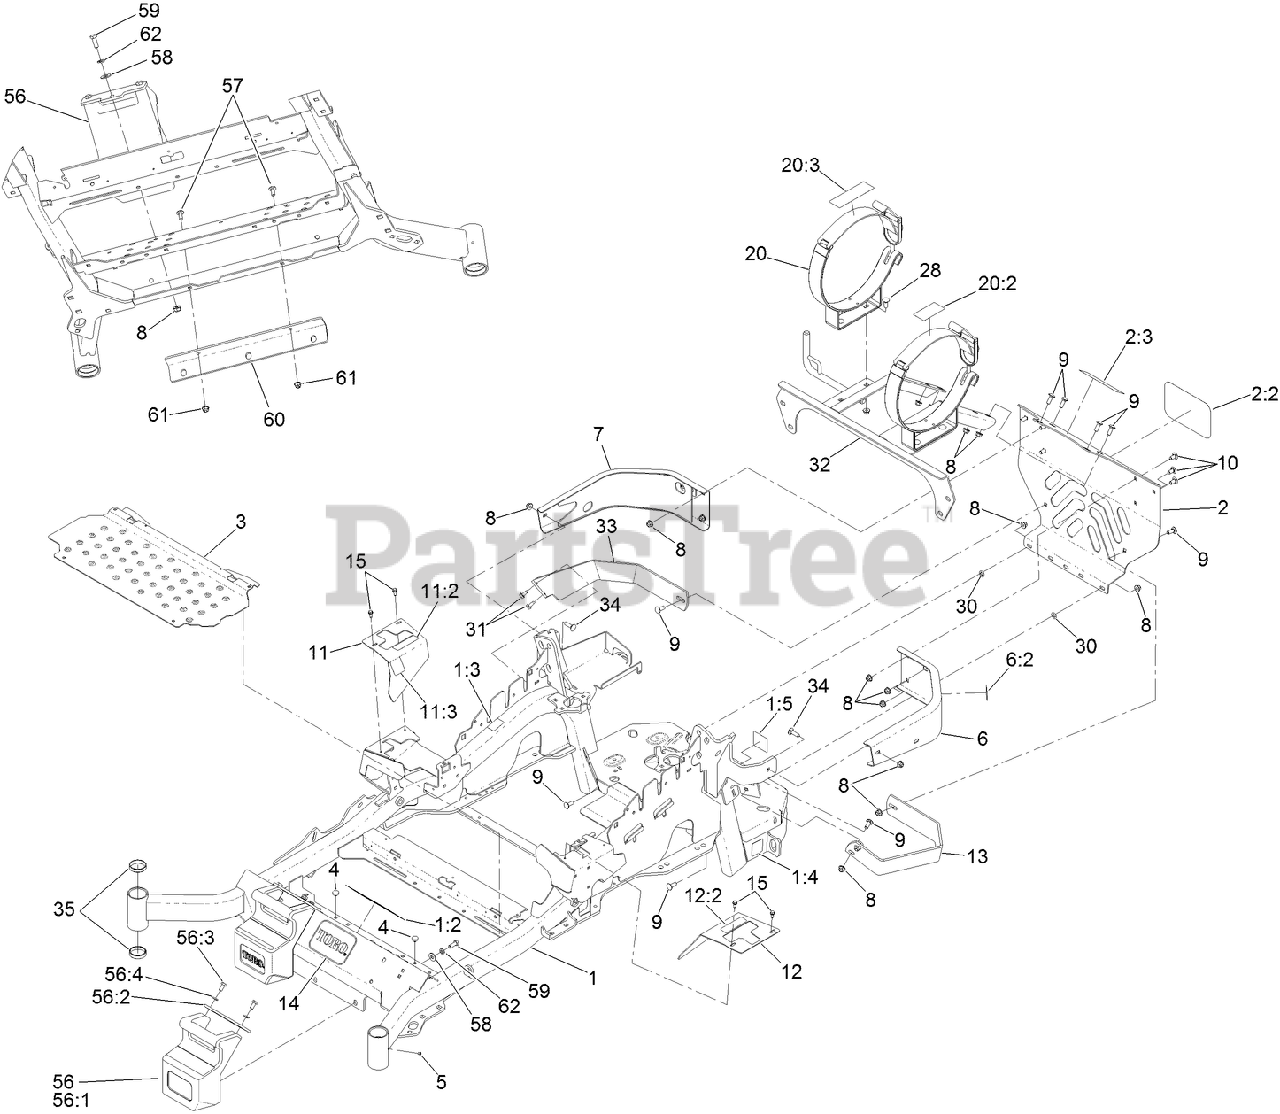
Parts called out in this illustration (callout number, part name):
1	MAINFRAME ASM
1:2	DECAL-DANGER
1:3	DECAL-WARNING
1:4	DECAL-HAZARD, PINCHED FINGER
1:5	DECAL-SPARK ARRESTER
2	LPG REAR GUARD ASM
2:2	DECAL
2:3	DECAL-LPG FUEL TANK REPLACEMENT
3	FLOORPAN
4	BUMPER
6	LH BUMPER ASM
6:2	DECAL-WARNING
7	BUMPER-RH
8	NUT-HF, NI
9	SCREW-CARR
10	SCREW-CARR
11	RH MOTION CONTROL COVER ASM
11:2	DECAL-CONTROL, MOTION
11:3	DECAL-PARK BRAKE, CE
12	LH MOTION CONTROL COVER ASM
12:2	DECAL-CONTROL, MOTION
13	GUARD-MUFFLER
14	DECAL
15	SCREW-HWH
20	TANK BRACKET ASM (SET)
20:2	DECAL-LPG WARNING
20:3	DECAL-LPG TANK SPEC
28	BOLT-CARR
30	NUT-PUSH
31	SCREW-HWHTF
32	SUPPORT-LPG TANK
33	STRAP-GUARD
34	BOLT-CARR
35	CUP-BEARING
56	WEIGHT ASM
56:1	WEIGHT-43 LB
56:2	TAB-SUPPORT, WEIGHT
56:3	SCREW-HH
56:4	WASHER-LOCK
57	SCREW-CARR
58	WASHER-FLAT
59	SCREW-HH
60	BRACKET-MOUNT, WEIGHT
61	NUT-HF, NI
62	WASHER-LOCK
